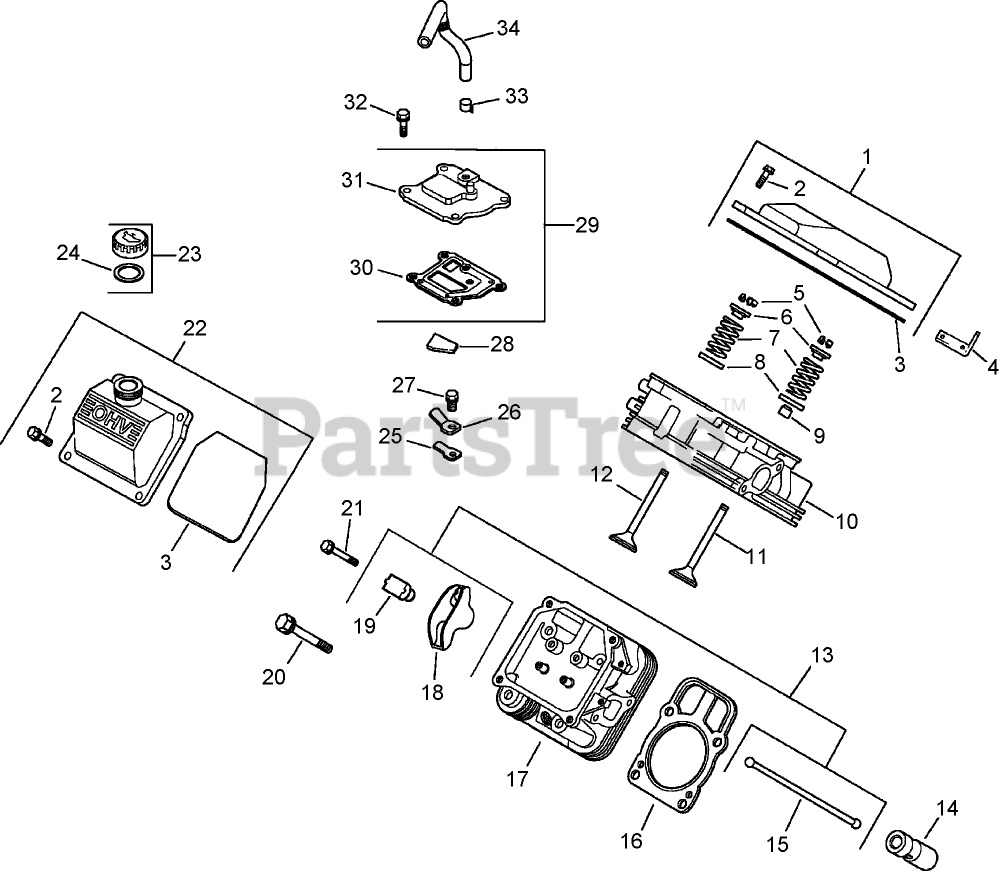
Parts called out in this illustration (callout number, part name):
1	Plain Valve Cover Kit (Includes 2, 3)
2	SCREW-FLANGE (M6X1.0X30)
3	O-Ring
4	STRAP-LIFTING
5	RETAINER KIT
6	CAP-SPRING, VALVE
7	SPRING-VALVE
8	RETAINER-SPRING
9	SEAL-STEM, VALVE
10	No. 1 Cylinder Head ASM
11	VALVE-INTAKE (STD)
11	VALVE-INTAKE (.25)
12	VALVE-EXHAUST (STD)
12	VALVE-EXHAUST (.25)
13	Valve Train Kit (Includes 15, 18, 19)
14	Lifter-Valve
15	ROD-PUSH
16	Cylinder Head Gasket Kit (Includes 20)
17	No. 2 Cylinder Head ASM
18	ARM-ROCKER
19	Pivot-Arm, Rocker
20	SCREW-FLANGE (M10X1.5X90)
21	Screw
22	Oil Fill Valve Cover Kit (Includes 2, 3)
23	Oil Fill Cap Kit (Includes 24)
24	O-RING
25	REED-BREATHER
26	RETAINER-REED
27	SCREW-HHFTF (M5X.80X10)
28	Filter-Breather
29	Breather Kit (Includes 30, 31)
30	GASKET-BREATHER
31	COVER-BREATHER
32	SCREW-HHFTF (M6X1.0X20)
33	CLAMP-HOSE, SPRING (1/2)
34	Hose-Breather
